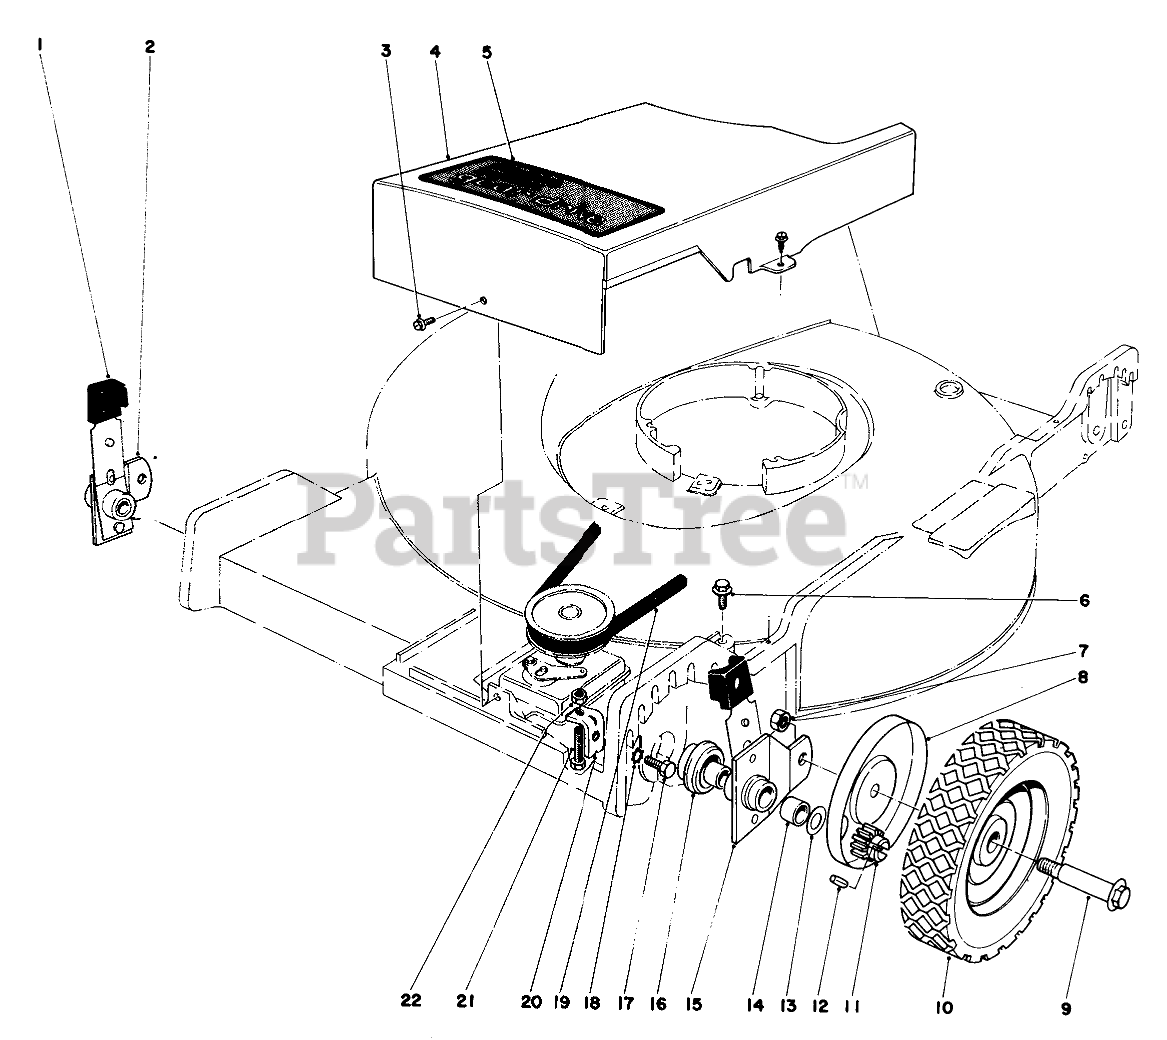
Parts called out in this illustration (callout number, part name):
1	KNOB-ARM
2	Pivot Arm (Incl. Ref. #14)
3	SCREW
4	Belt-Cover
5	Decal Belt Cover
6	SCREW-HWHTF
7	Nut
8	WHEEL COVER
10	Wheel & Tire
11	Pinion
12	PIN-GROOVED
13	WASHER-THRUST
14	BUSHING
15	Pivot Arm (Incl. Ref. #14)
16	End Cap
17	SCREW-HH
18	WASHER-LOCK
19	V-BELT
20	Bracket-Gear Box
21	SCREW
22	NUT-LOCK
